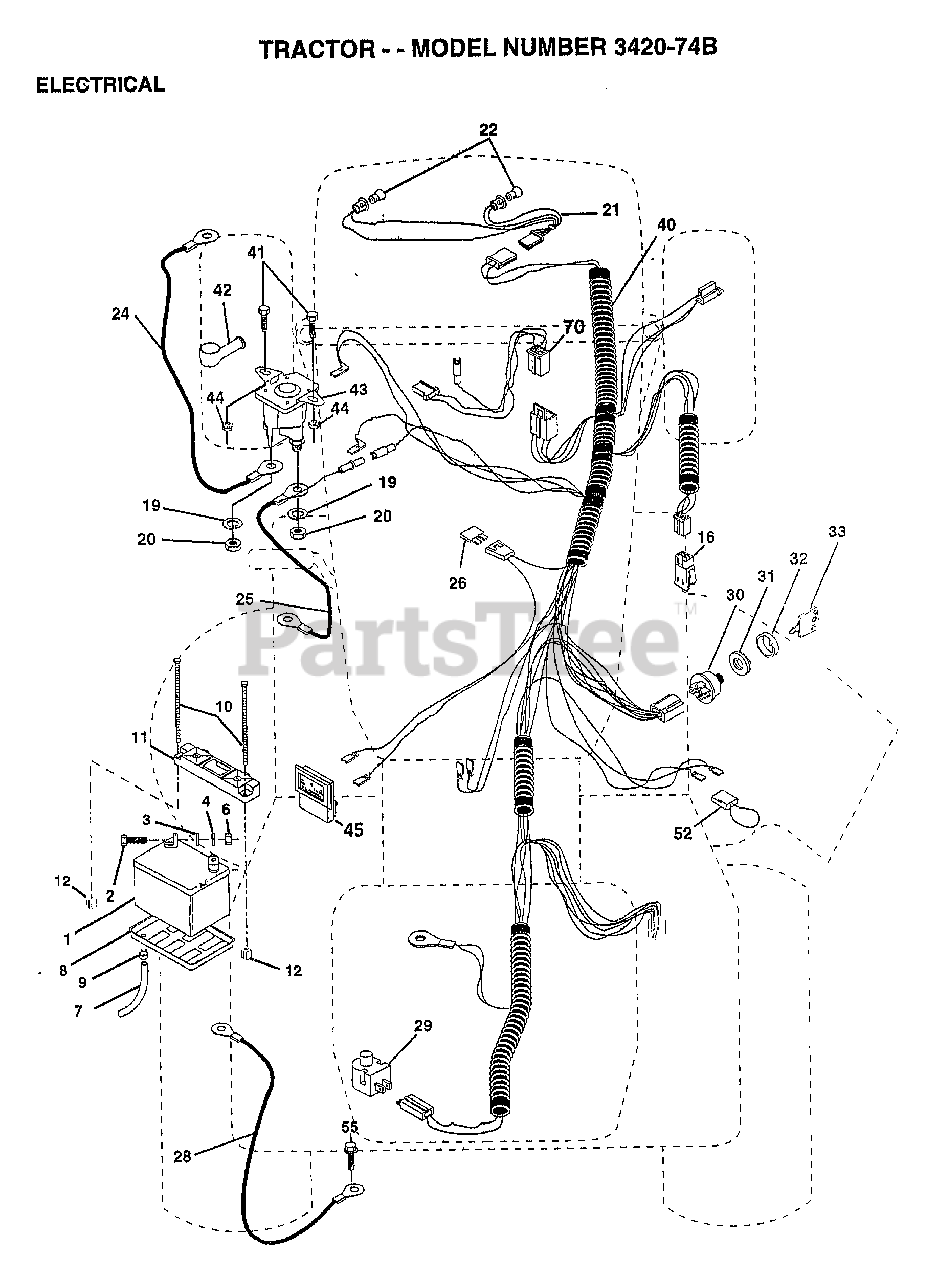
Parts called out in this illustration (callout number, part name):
2	BOLT LT
3	WASHER
4	LOCKWASHER
7	"DRAIN TU T, BATT"
8	"TRAY T, BATTERY"
9	HOSE CLAMP T
11	HOLDDOWN BATTERY
16	SWITCH INTERLOCK
20	NUT
21	"HARNESS,LIGHT SOC"
22	HEADLAMP BULB
24	"CABLE T, BATTERY"
25	CABLE.6GA.22W/16W
26	FUSE HYT
28	CABLE.GRND.6GA.21
29	SWITCH SEAT
30	SWITCH IGN 4POS
31	NUT IGNITION
32	COVER KEY SWITCH
33	KEY
40	"HARNESS-IGN,YDPRO"
41	BOLT HXHD FIN
44	NUT HXKEP 1/4X20
52	PROTECTION LOOP
55	SCREW LT
70	HARNESS ENG DUAL
